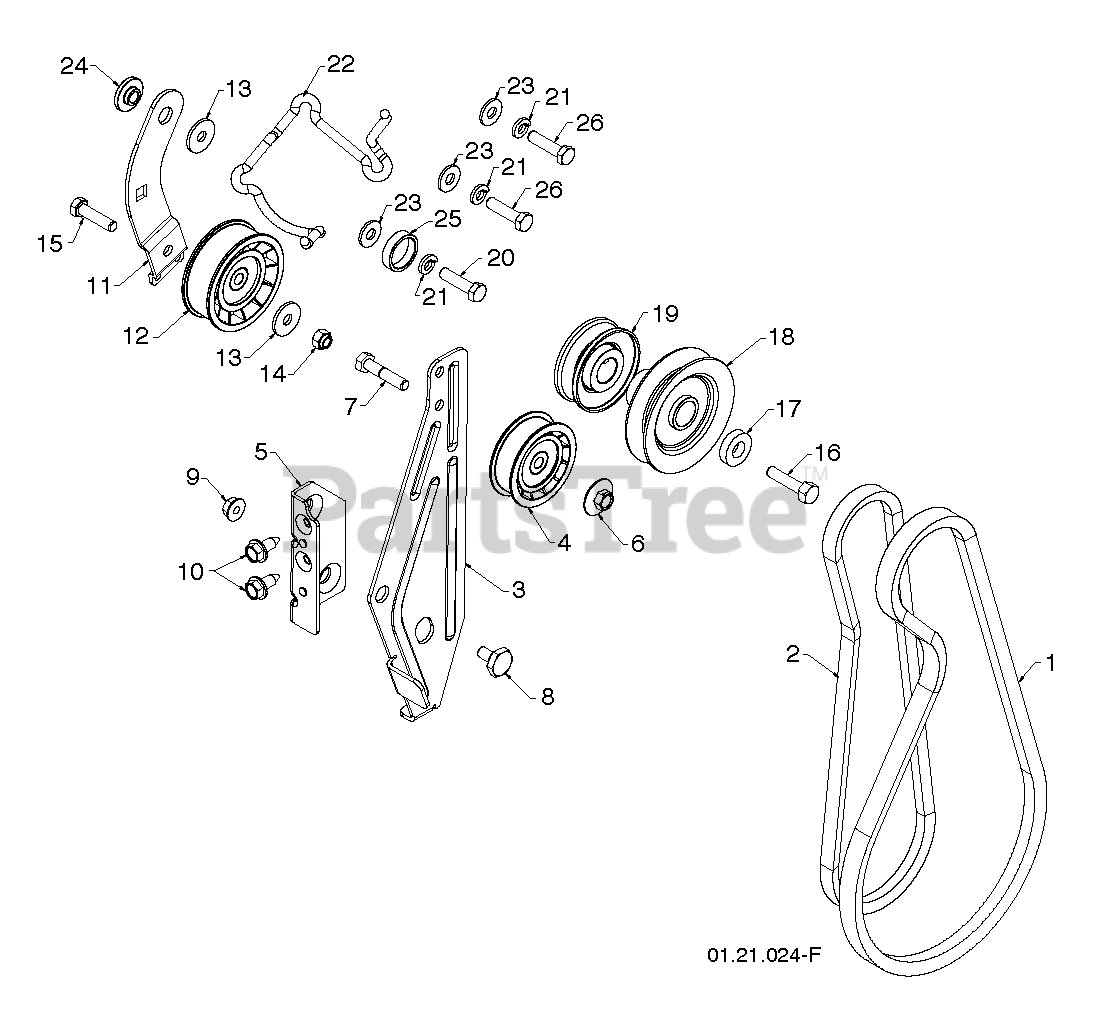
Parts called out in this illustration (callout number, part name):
1	BELT.V.IMPELLER
2	V-BELT.TRACTION.HYDRO.II.SNOW
3	ARM.IDLER.BRAKE.
4	PULLEY.W/SPACER.2.75
5	RP BRACKET.IDLER.PIVOT
6	NUT.FLANGE.HEX.5/16X18.BLACK
7	HEX BOLT
8	BOLT.SHOULDER.1/2X12
9	NUT.LOCK.5/16-18
10	BOLT.5/16HEX.WHS.HD
11	ARM, IDLER
12	PULLEY.W/SPACER.2.75
13	STEEL WASHER
14	NUT.71038.31-18.HEX.NYLOCK
15	BOLT.5/16-18X1-1/4 FULL.THREAD
16	SCREW, HEX HD 3/8-24 X 1-3/8
17	WASHER, FLAT 3/8
18	PULLEY.IMPELER.
19	PULLEY,ENGINE TRACTION DRIVE
20	CAPSCREW.HEXHD.5/16X1.25.
21	LOCKWASHER
22	GUIDE.BELT.HYDRO.LS.SNOW
23	WASHER.20X8.5
24	RP BUSHING, IDLER PIVOT
25	SPACER.ENGINE.PULLEY
